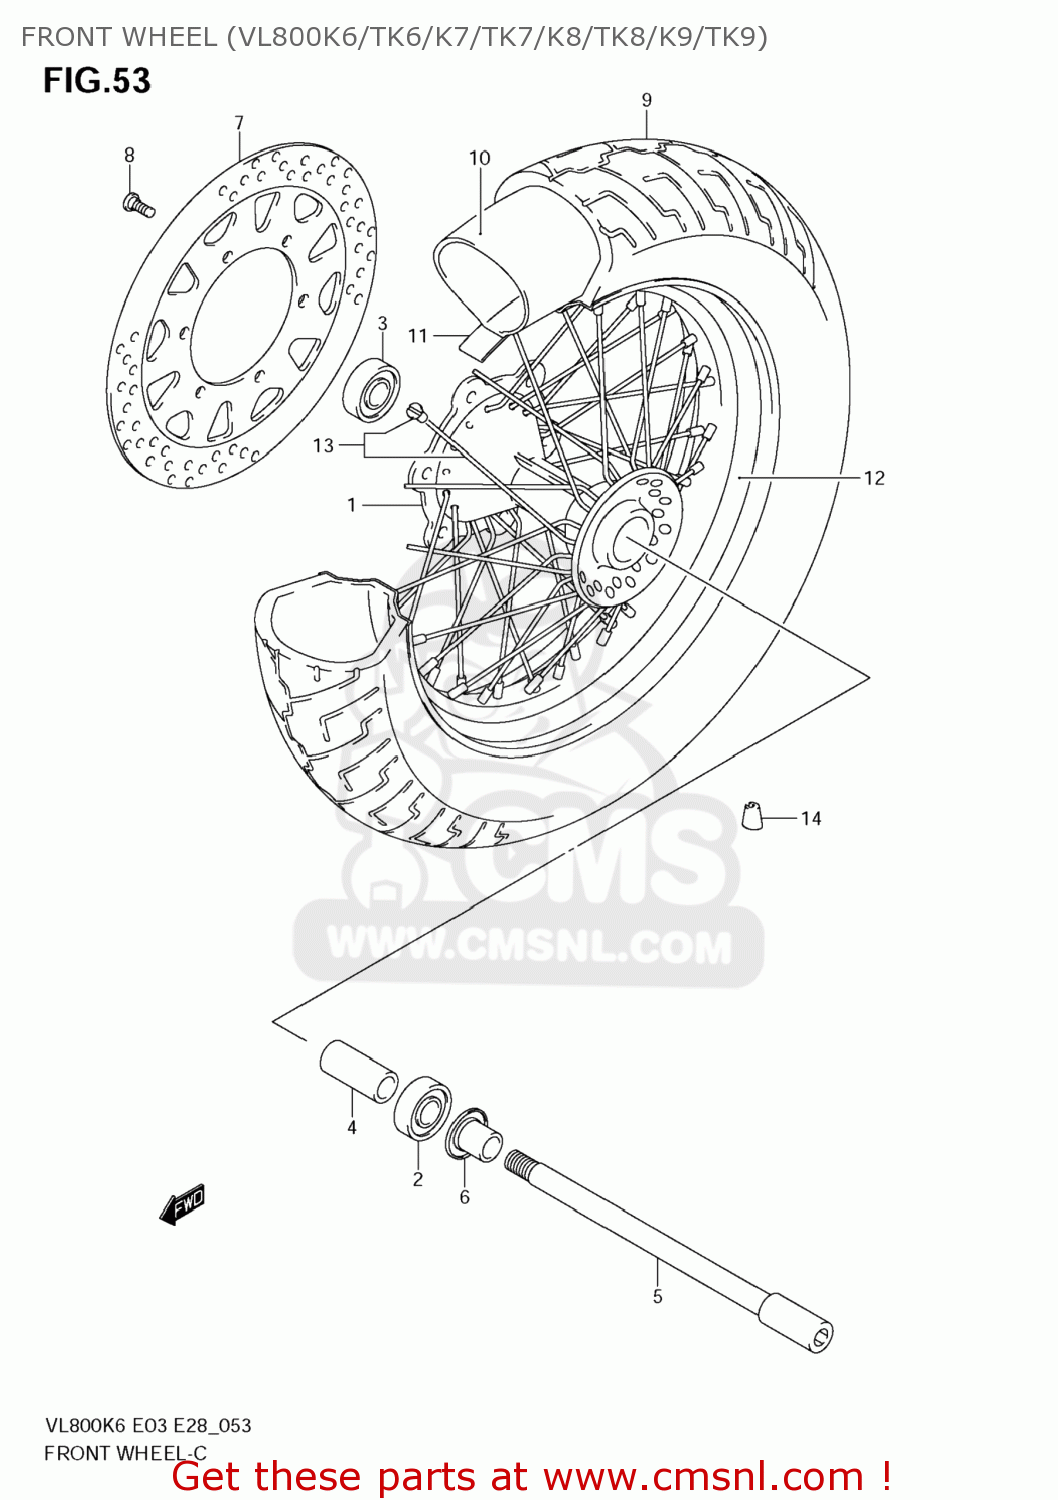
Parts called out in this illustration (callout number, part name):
1	HUB,FR
2	BEARING
3	BEARING
4	SPACER(17.5X25X102)
5	AXLE,FR
6	SPACER,FR AXLE,R
7	DISC,FR BRAKE
8	BOLT,DISK
9	TIRE(130/90 16 67H)
10	TUBE ASSY,WHEEL INNER
11	PROTECTOR,WHL INR TUBE
12	RIM,FR WHEEL(16M/CXMT3.00)
13	SPOKE SET,FR WHEEL
14	BALANCER,WHEEL(15G)
